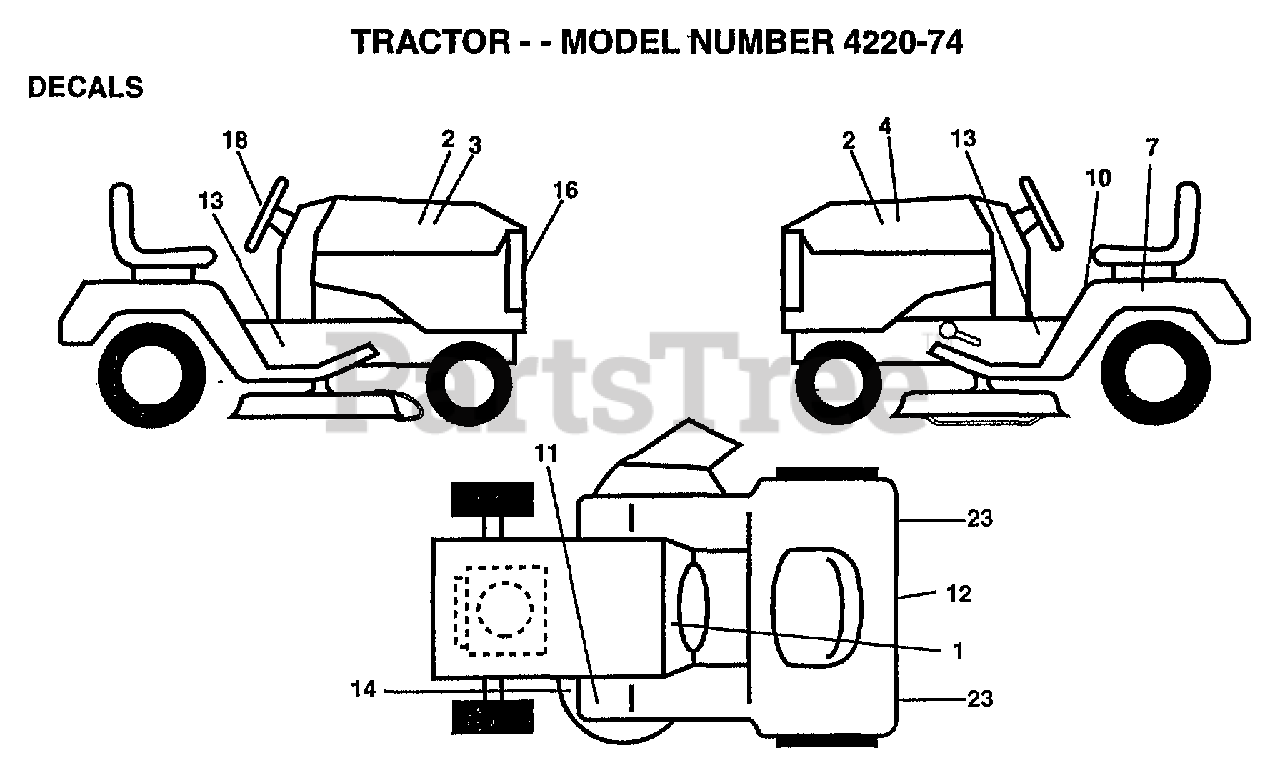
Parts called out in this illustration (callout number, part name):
1	"DECAL-OPER,GEAR D"
2	NAMEPLATE LOGO
4	HOOD DECAL LH
5	DECAL BRAK PARK
7	DECAL.BATRY.3-3908
10	"DECAL DANGER,FEND"
13	DECAL CHASSIS
14	"DECAL.V.BELT.44"""
16	GRILL DECAL
23	REFLECTOR-TAIL YT
